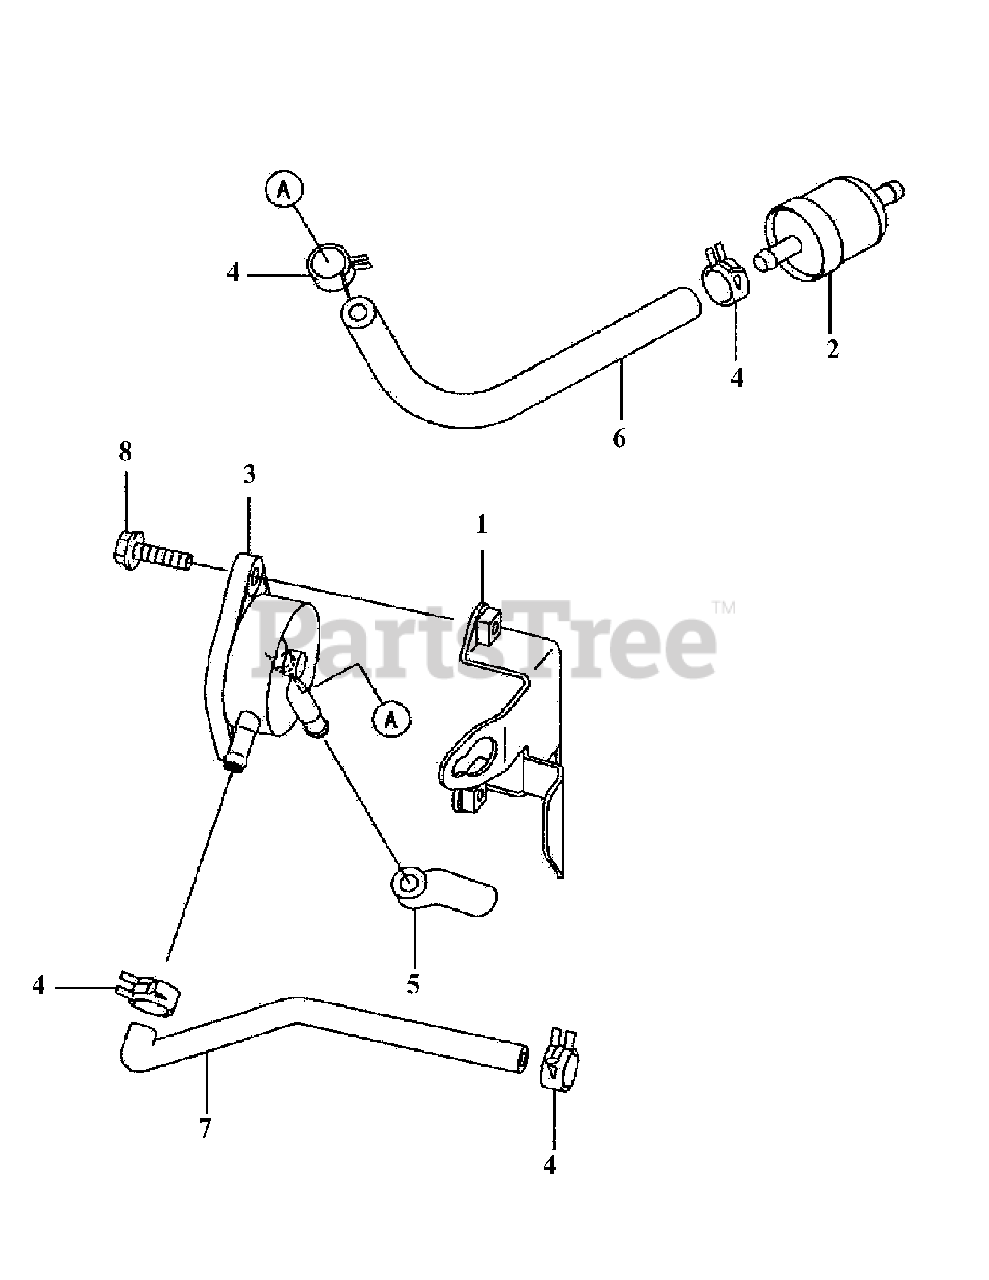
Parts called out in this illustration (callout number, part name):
1	Bracket, compl
2	Filter, Fuel
3	Pump, Fuel
4	Clamp
8	Bolt, Flanged
